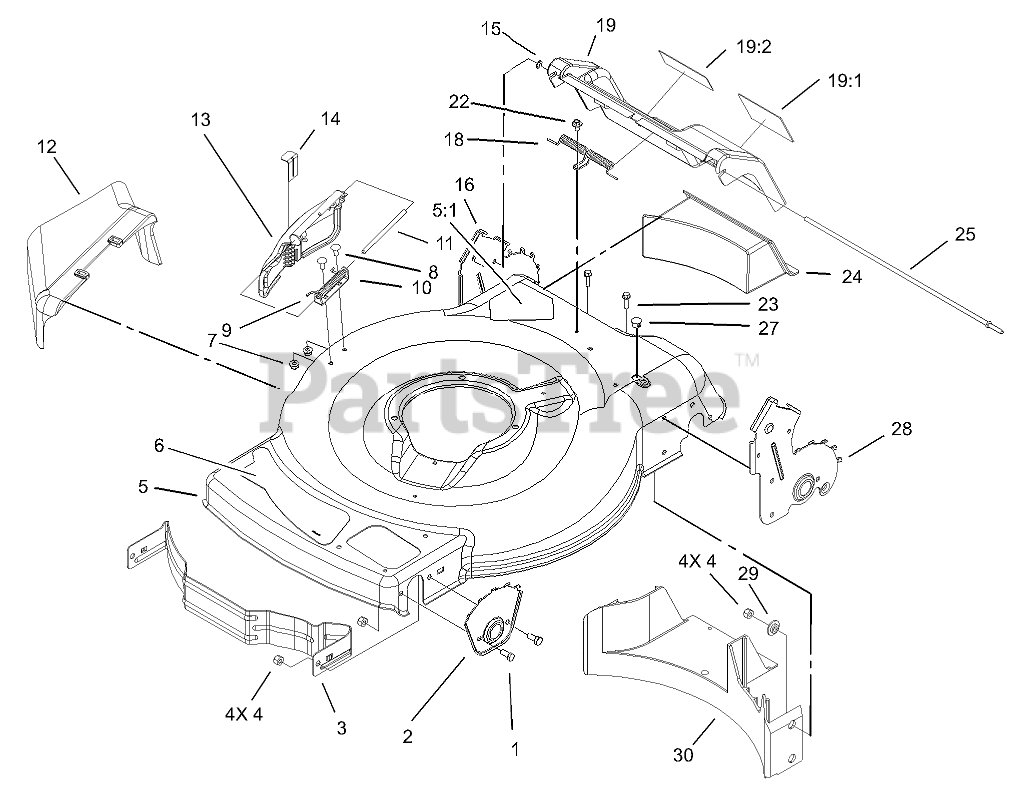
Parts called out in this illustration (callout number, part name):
1	SCREW-HH
2	Plate-HOC, Front
3	Baffle-Front
4	NUT-LOCK, NI
5	Housing (only on: 20013)
5	Housing (only on: 20017)
5:1	Decal-Danger, Cut Finger (only on: 20013)
5:1	Decal-Danger (only on: 20017)
6	Decal-Deck
7	NUT-HHF
8	SCREW-CARR
9	SPRING-TORSION
10	BRACKET-COVER
11	ROD-COVER
12	CHUTE-DISCHARGE, SIDE
13	Door-Discharge, Side
14	Lever-Latch
15	NUT-PUSH
16	RH REAR HOC PLATE ASM (only on: 20013)
18	Spring-Door, Rear
19	Door (only on: 20013)
19	Door (only on: 20017)
19:1	Decal-Warning (only on: 20013)
19:2	Decal Warning (only on: 20013)
19:2	Decal-Warning, Door (only on: 20017)
22	SCREW AND WASHER ASM
23	SCREW-HWH
24	Plug-Discharge, Rear
25	Rod-Pivot, Rear Door
27	Plug-Dome
28	LH REAR HOC PLATE ASM (only on: 20013)
29	Washer-Stepped
30	Baffle-Rear
